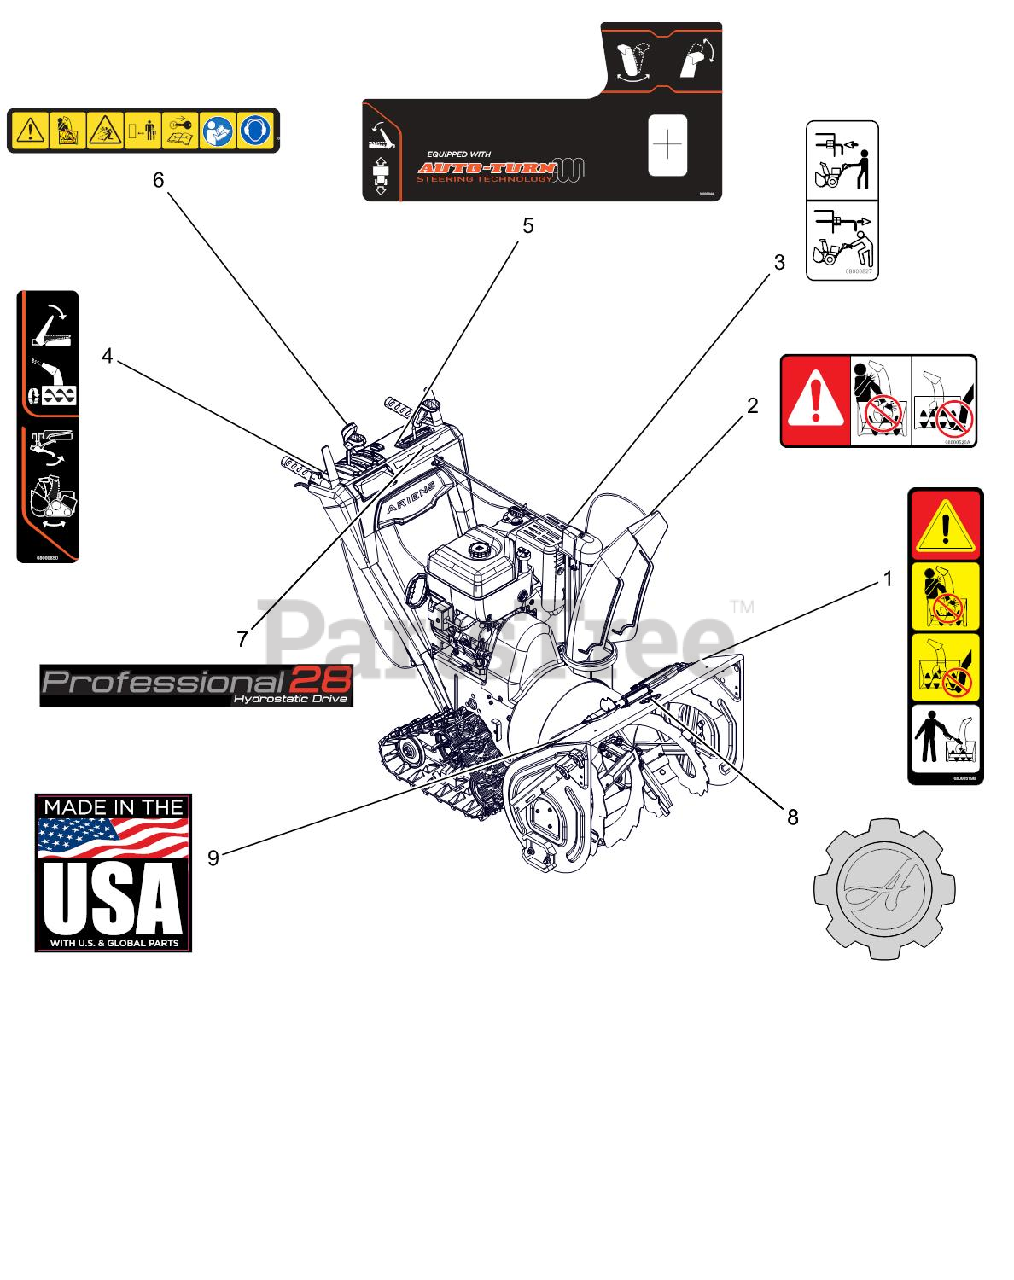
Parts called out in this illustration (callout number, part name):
1	DECAL, DANGER - ROTATING PARTS
2	DECAL, DANGER
3	DECAL, BYPASS
4	DECAL,CONTROL-RH TRACK
5	DECAL,CONTROL-LG QT2
6	DECAL,DASH - SAFETY
7	DECAL, DASH - PRO HYDRO 28
8	DECAL, ARIENS-GEAR BADGE
9	DECAL, MADE IN USA
